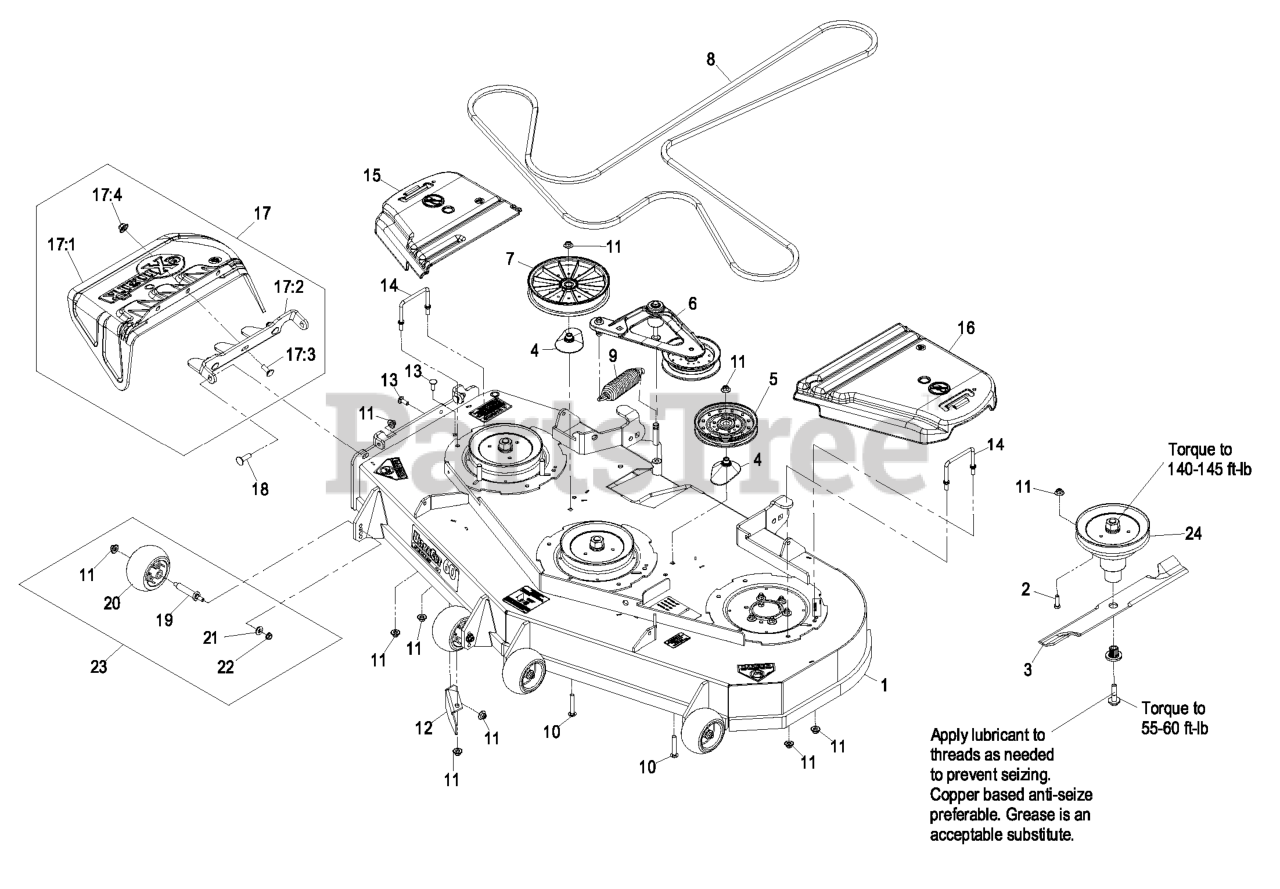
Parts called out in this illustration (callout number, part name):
1	DECK W/ DECALS ASM-604
2	SCREW-HH
4	SPACER-PULLEY
7	PULLEY,IDLER 8"FLAT
8	BELT,V-5V-198.75
10	SCREW-CARR
11	Nut-Nyloc 3/8-16 Flg
12	BAFFLE,DISCHARGE 52/60
13	SCREW-CARR
14	WIREFORM-COVER
15	COVER-BELT, RH
16	COVER-BELT, LH
17	ASM,DISCHARGE CHUTE
17:1	CHUTE,DISCHARGE
17:2	BRACKET,DISCHARGE CHUTE
17:3	SCREW-CARR
17:4	Nut-Nyloc 3/8-16 Flg
18	Bolt-Carriage 3/8-16 X 1 1/4
20	ROLLER-SCALP, ANTI
21	WASHER-BELLEVILLE
22	NUT-HHF, WHIZ
24	KIT,CUTTER HOUSING 60
25	Asm, Deck Complete 604
